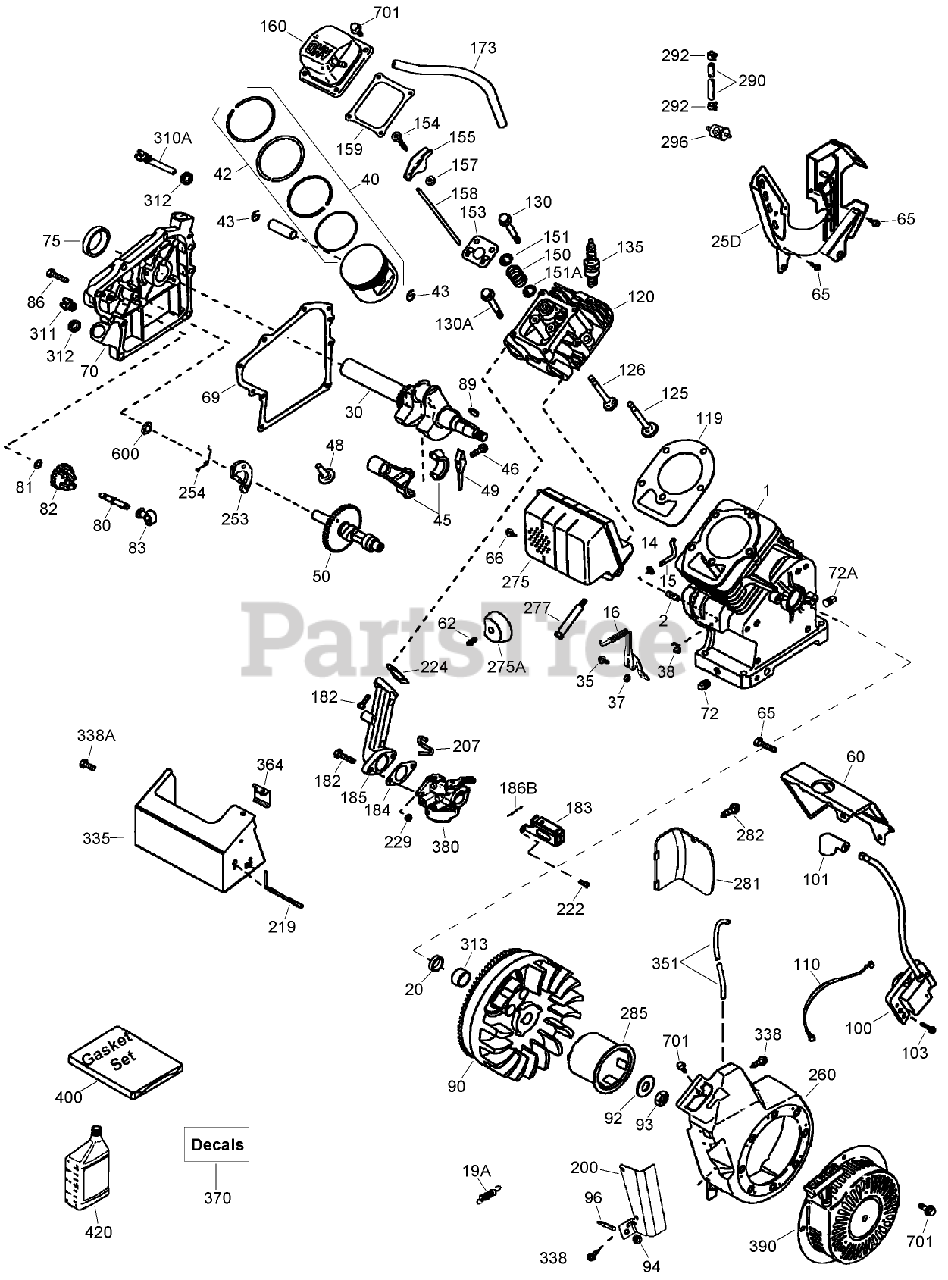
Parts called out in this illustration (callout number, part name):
135	Spark Plug-Resistor (R N 4C)
150	Spring-Valve
151	Cap-Valve, Spring
151A	Seal-Valve, Intake
153	Guide-Rod, Push
154	Stud-Arm, Rocker
155	Arm-Rocker
157	Nut (1/4-28)
158	Rod-Push
159	Gasket-Cover, Rocker Arm
160	Cover-Arm, Rocker
173	Breather Tube
182	Screw (1/4-20 x 1)
183	Bracket-Choke
184	Gasket
185	Pipe-Intake
186B	Spring-Choke
200	Bracket-Control
207	Link-Throttle
219	Rod-Choke
222	Screw (10-32 X 15/32)
224	Gasket-Pipe, Intake
229	Nut (1/4-20)
253	Weight-Release, Compression
254	Spring-Release, Compression
260	Housing-Blower
275	Muffler (Carburetor Side Discharge)
275A	Deflector-Muffler
277	Screw (1/4-20 x 2-9/32)
281	Cover-Bubble, Starter
282	Screw (6-32 x 25/64)
285	Cup-Starter
290	Line-Fuel, Low Permeation (16.0)
292	Clamp-Line, Fuel
296	Filter-Fuel (also available in Packaged Part 740093) (Includes 292)
310A	Dipstick (Includes 312)
311	Plug-Fill, Oil (Includes 312)
312	Gasket
313	Spacer
335	Cover-Carburetor
338	Screw (10-32 x 1/2)
338A	Screw (10-32 x 3/8)
351	Line-Primer
364	Bracket-Cover, Carburetor
370	Decal-Tecumseh Logo for Top of Recoil Starter
380	Carburetor (Includes 184)
390	Starter-Rewind
400	Gasket Set
420	Oil-Engine, S A E 5W30
600	Washer
701	Screw (1/4-20 x 31/64)
999	Winter Maintenance Kit (S A E 5W30 Oil)
